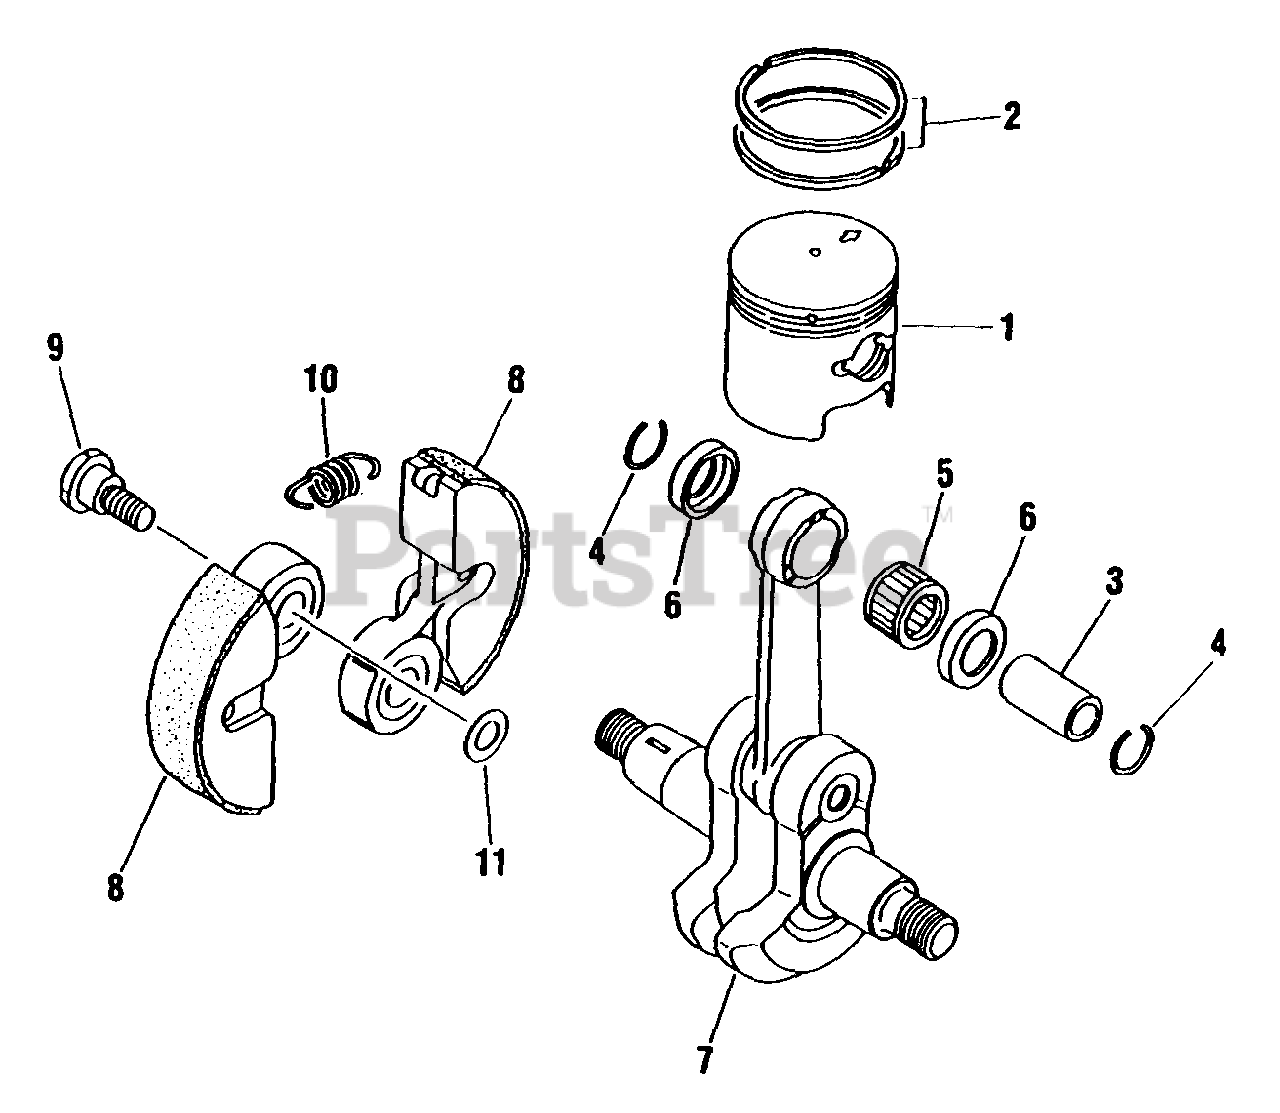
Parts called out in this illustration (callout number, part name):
2	RING, PISTON
3	PIN, PISTON
4	RING, RETAINING
5	BEARING, NEEDLE
6	WASHER, THRUST
7	CRANKSHAFT ASSY
8	SHOE, CLUTCH
9	BOLT, CLUTCH
10	SPRING, CLUTCH
11	WASHER - 6
